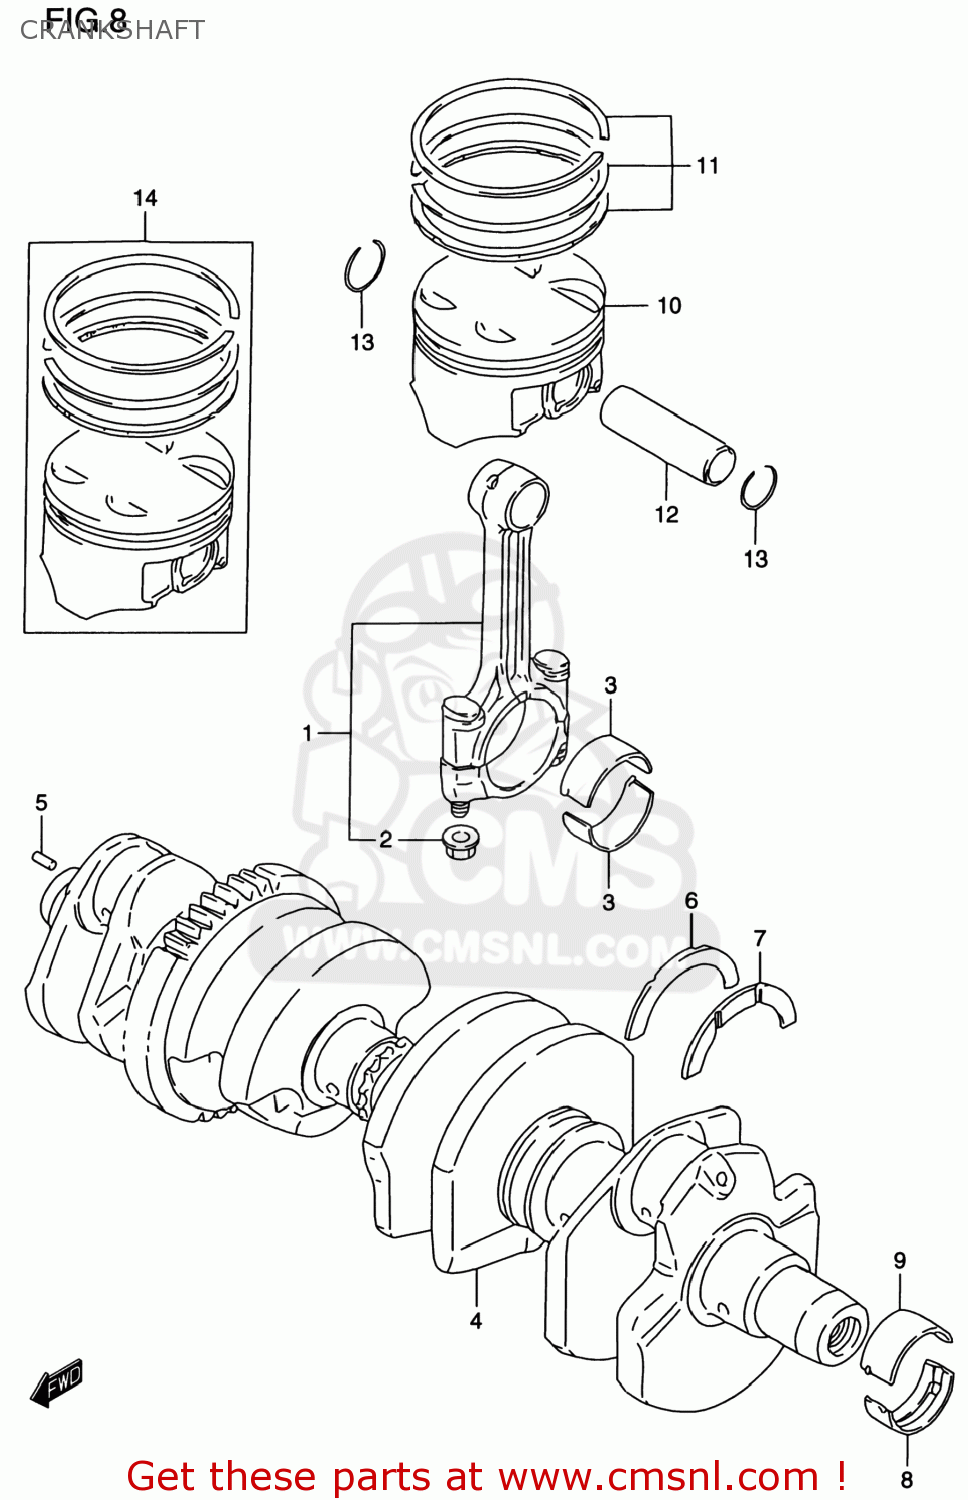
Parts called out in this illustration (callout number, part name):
1	CONNECTING ROD ASSY
2	NUT
3	BEARING,CRANK PIN
4	CRANKSHAFT SET
5	PIN
6	BEARING,CRANK THRUST(GREEN)
7	BEARING,CRANK THRUST(RED)
8	BEARING,CRANKSHAFT LWR
9	BEARING,CRANKSHAFT UPR
10	PISTON
11	RING SET,PISTON
12	PIN,PISTON
13	CIRCLIP,PISTON PIN
14	PISTON SET (OS:0.5)
